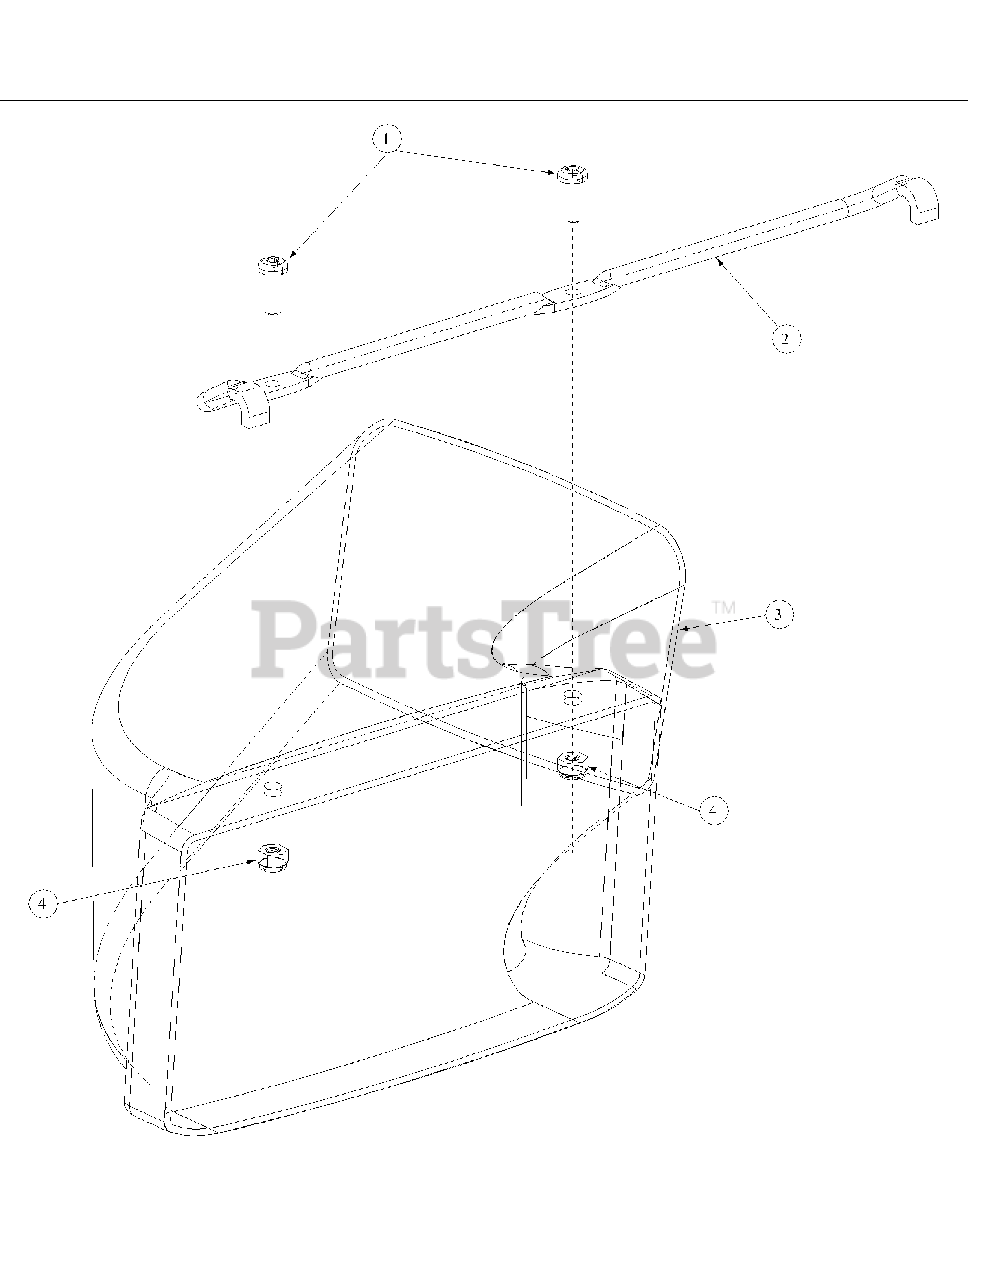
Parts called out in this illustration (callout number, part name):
1	Machine Screw, 1/4-20, .750, PANTRXI
2	21" Side Chute Mounting Rod
3	21" Side Chute Spiral Deck
4	Hex Nut 1/4-20, GRC, Lock
